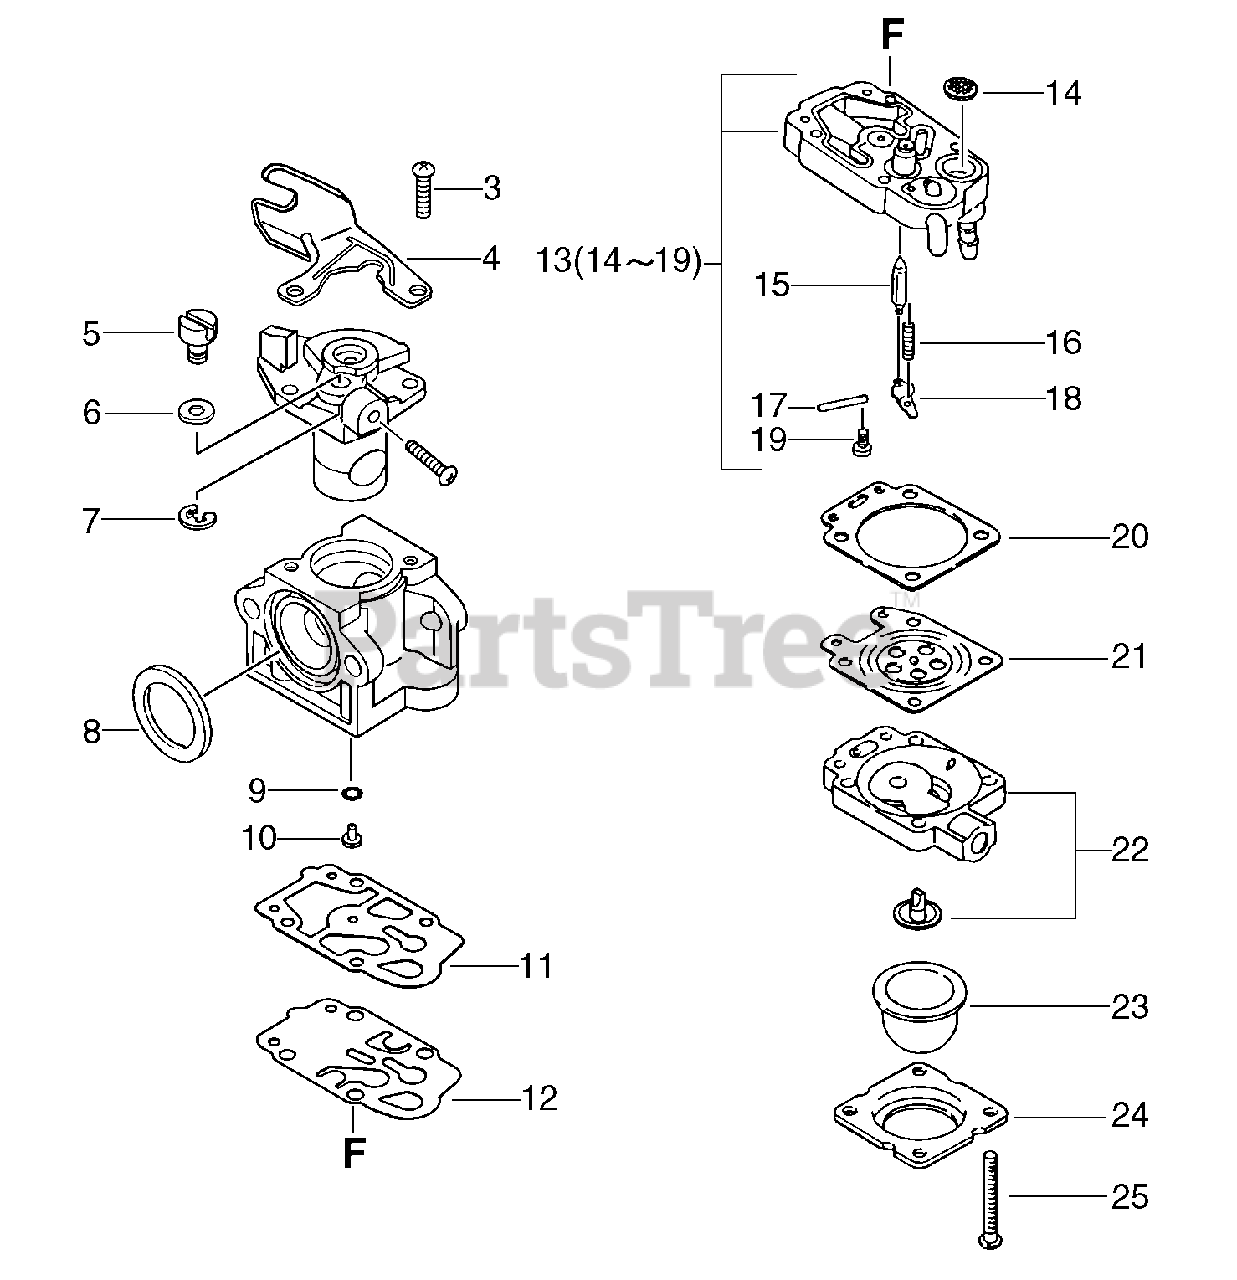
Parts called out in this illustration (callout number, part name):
4	BRACKET, THROTTLE CABLE
8	RING, PACKING
9	O-RING
10	JET, MAIN
11	GASKET, PUMP
12	DIAPHRAGM, FUEL PUMP
13	BODY ASSY, PUMP
14	SCREEN, FUEL INLET
15	VALVE, INLET NEEDLE
16	SPRING, METERING LEVER
17	PIN, METERING LEVER
18	LEVER, METERING
20	GASKET, METERING DIAPHRAGM
21	DIAPHRAGM, METERING
22	BODY ASSY, PURGE
23	BULB, PURGE
24	RETAINER, PURGE BULB
